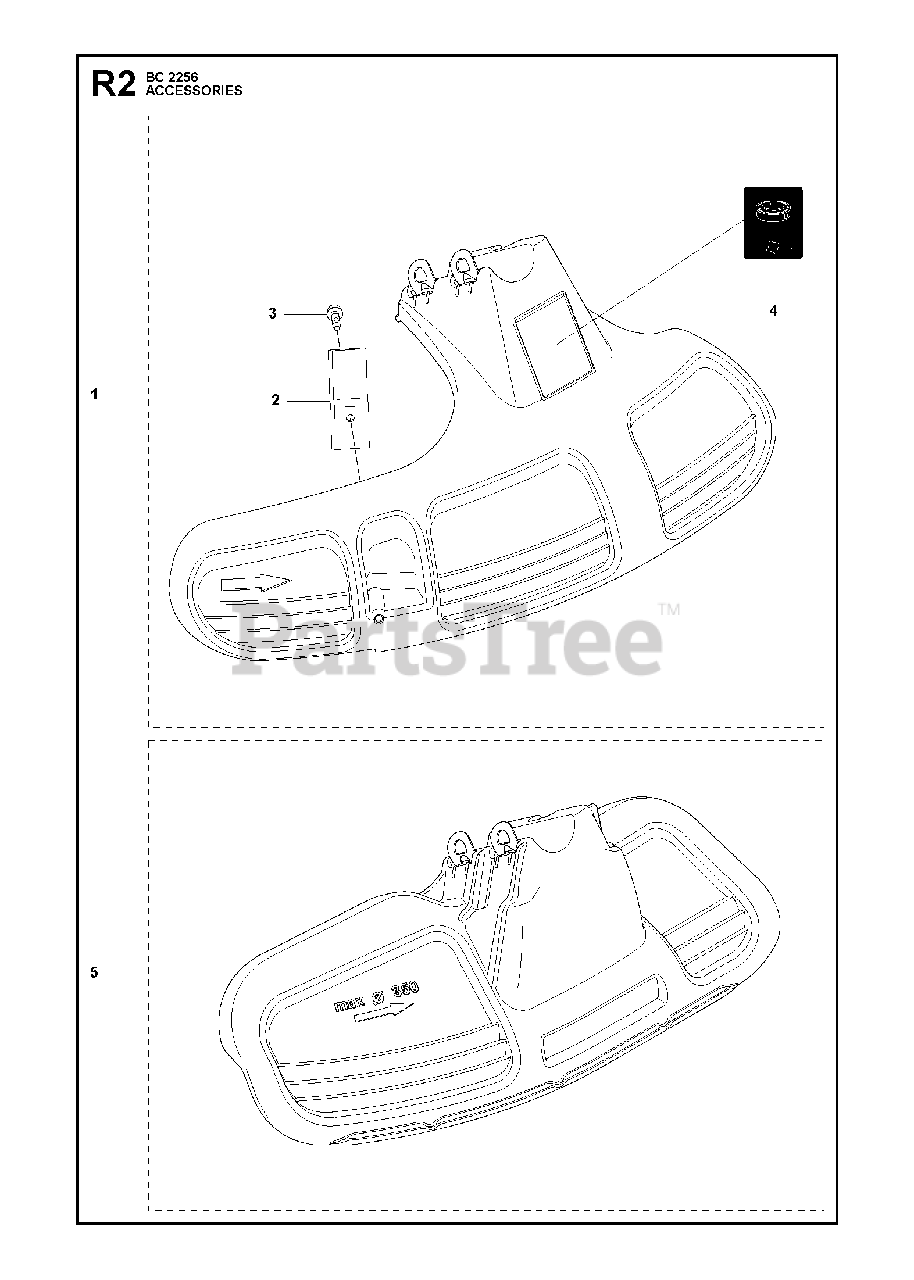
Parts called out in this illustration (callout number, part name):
2	BLADE
3	SCREW
4	DECAL
